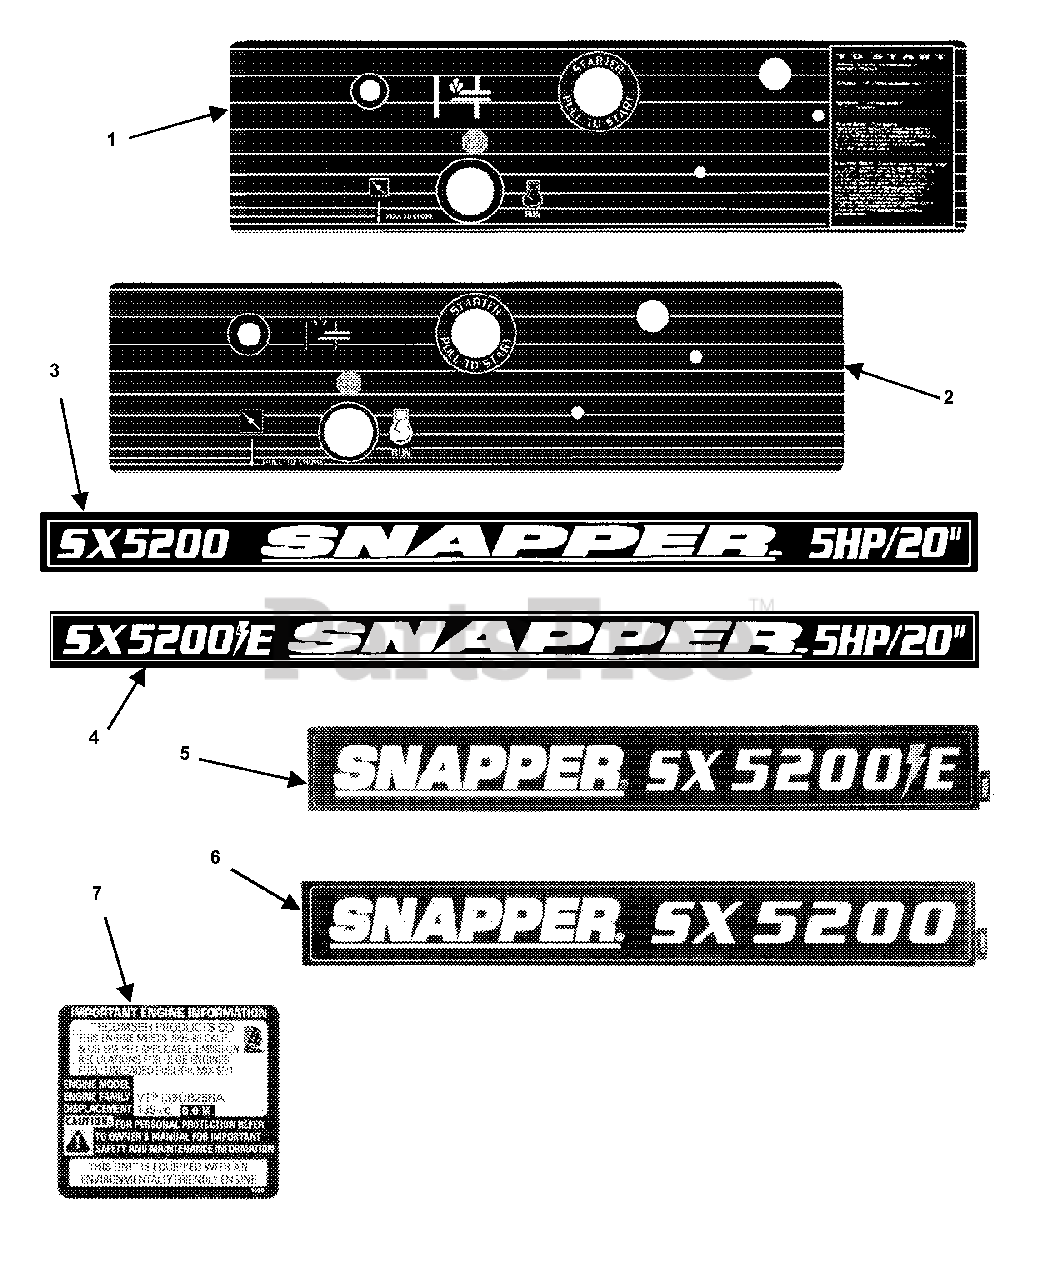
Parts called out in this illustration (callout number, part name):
1	DECAL, Control Panel
2	DECAL, Control Panel Recoil/ES
3	DECAL, Model, Auger Housing (Recoil)
4	DECAL, Model, Auger Housing (Electric Start)
5	DECAL, Model (Electric Start)
6	DECAL, Model (Recoil)
7	DECAL, Tecumseh 5HP CARB/EPA Certified
